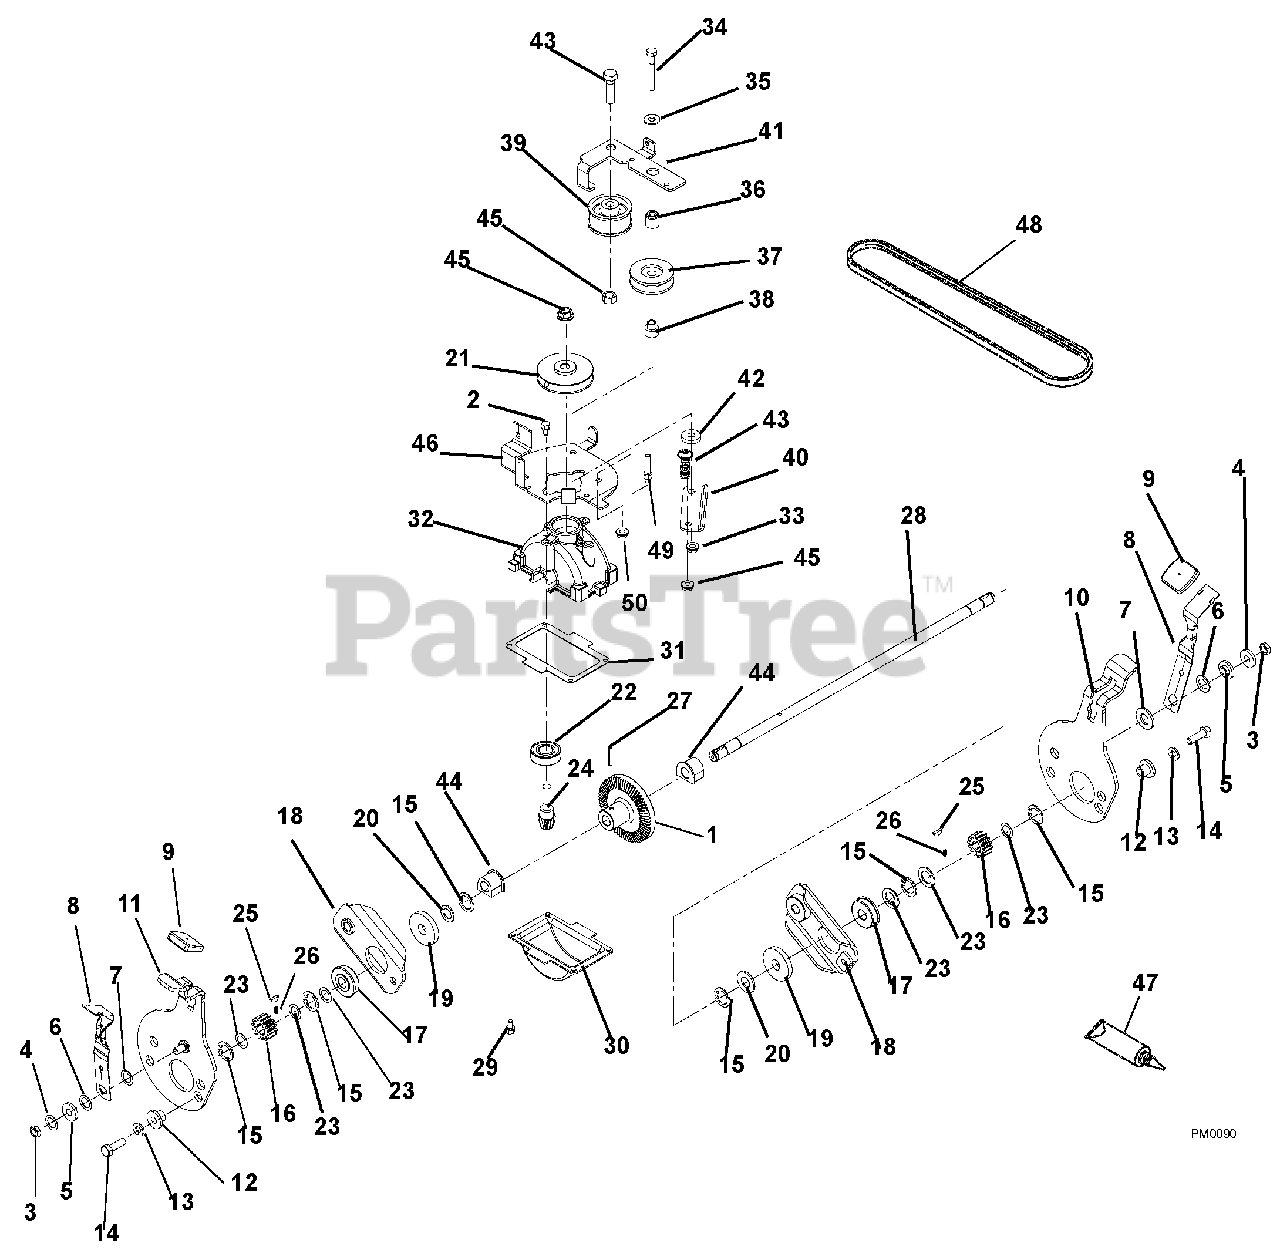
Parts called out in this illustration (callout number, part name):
1	GEAR, REDUCTION
2	@SCR-TAP 10-24X.375 HWH YZ TR
3	@NUT-LK-CTR .31-18 YWZC
4	@WSHR-FL-STL.38X.875X.083 YWZC
5	BSHG-FLG .265X.437X.250X.750
6	WSHR-FL-STL .52X.827X.062 YWZC
7	WSHR-FL-STL .630X1.005X.062 YZ
8	LEVER, HEIGHT ADJUSTMENT
10	WELDMT-DETENT SUPPORT RIGHT
11	WELDMT-DETENT SUPPORT LEFT
12	BSHG-FLG .325X.500X.513X.875
13	@WSHR-LK .31X.078 REG YWZC
14	@BLT-HEX .31-18X1.00 GR5 YWZC
15	RG-RTNG-EXT.50 X .034
16	PINION-WBLM DRIVE
17	BRG-BALL .50X1.38X.438 SEALED
18	ARM,WHEEL MOUNT
19	WSHR-FL-STL .515X1.625X.250 YZ
20	@WSHR-FL-STL.531X1.06X.095YWZC
21	PULLEY, TRANS INPUT
22	BRG-BALL .625X1.375X.43
23	WASHER, .500X.750X.020 THRUST
24	PINION, GEARBOX INPUT
25	KEY-WDRF .125X.50X.20 (HRDEND)
26	SPRING, .134X.180X.144 COMP.
28	SHAFT - TRANSMISSION OUTPUT
29	@SCR-TAP 10-24X.375 HWH YZ TR
30	SUMP, GEARBOX
31	GASKET, TRANSMISSION
32	HOUSING, WBLM GEAR BOX
33	@NUT-LK-TOP-FLG .25-20 YWZC
34	BLT-HEX .25-20X2.25 GR8 YWZC
35	@WSHR-FL-STL.312X.734X.065 YWZ
36	SPACER, IDLER ARM
37	IDLER, 3L FRONT SIDE .38X1.875
38	SPACER, V-IDLER PULLEY
39	IDLER - FLAT 1.875OD X .75WIDE
40	STRAP,TRANSMISSION
41	ARM-TRANS IDLER
42	@WSHR-FL-STL.406X.812X.065 YWZ
43	@BLT-HEX .38-16X1.25 GR5 YWZC
44	BUSHING, TRANS OUTPUT SHAFT
45	@NUT-LK-TOP-FLG .38-16 YWZC
46	BRACKET, TRANSMISSION CONTROL
47	LUBRICATE
48	V-BELT, 3L-WRAPPED
49	FINGER, BELT
50	@NUT-SPNLK-FLG .25-20 YWZC
